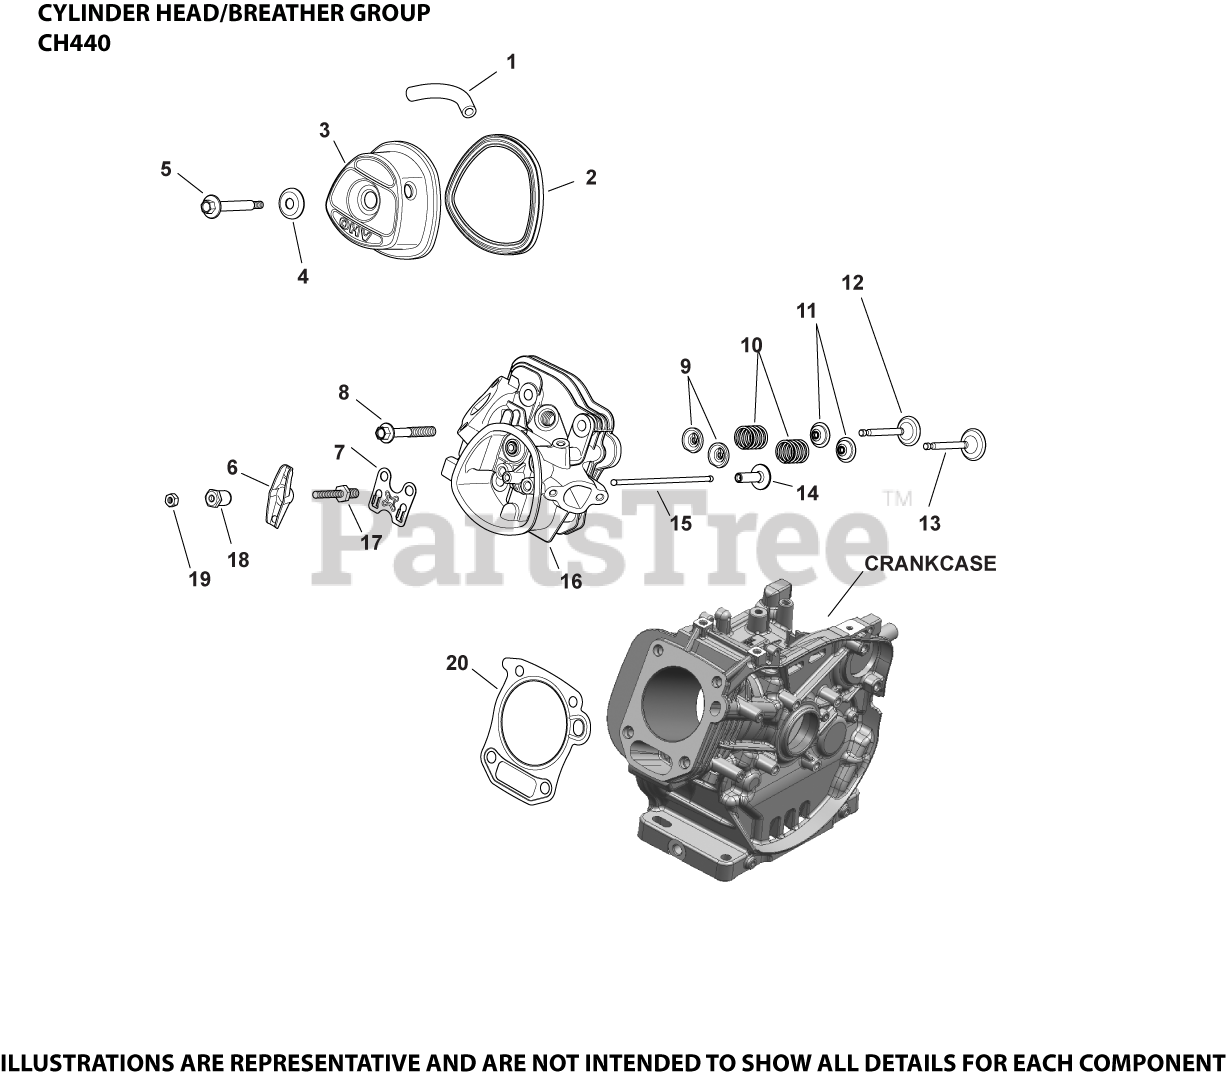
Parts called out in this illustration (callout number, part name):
1	TUBE, BREATHER
2	GASKET, VALVE COVER
3	KIT, VALVE COVER ASSEMBLY
5	SCREW, VALVE COVER SEAL ASSY
6	ARM, ROCKER
7	PLATE, PUSHROD GUIDE
8	SCREW, HEX FLANGE CYLINDER HEAD (CKY)
9	RETAINER, VALVE SPRING
10	SPRING, VALVE
11	SEAL, VALVE STEM
12	VALVE, EXHAUST
13	VALVE, INTAKE
14	LIFTER, VALVE
15	ROD, PUSH
16	KIT, CYLINDER HEAD
17	STUD, ROCKER ARM - (#1407222S)
18	PIVOT, ROCKER ARM
19	NUT, HEX JAM
20	KIT, HEAD GASKET
